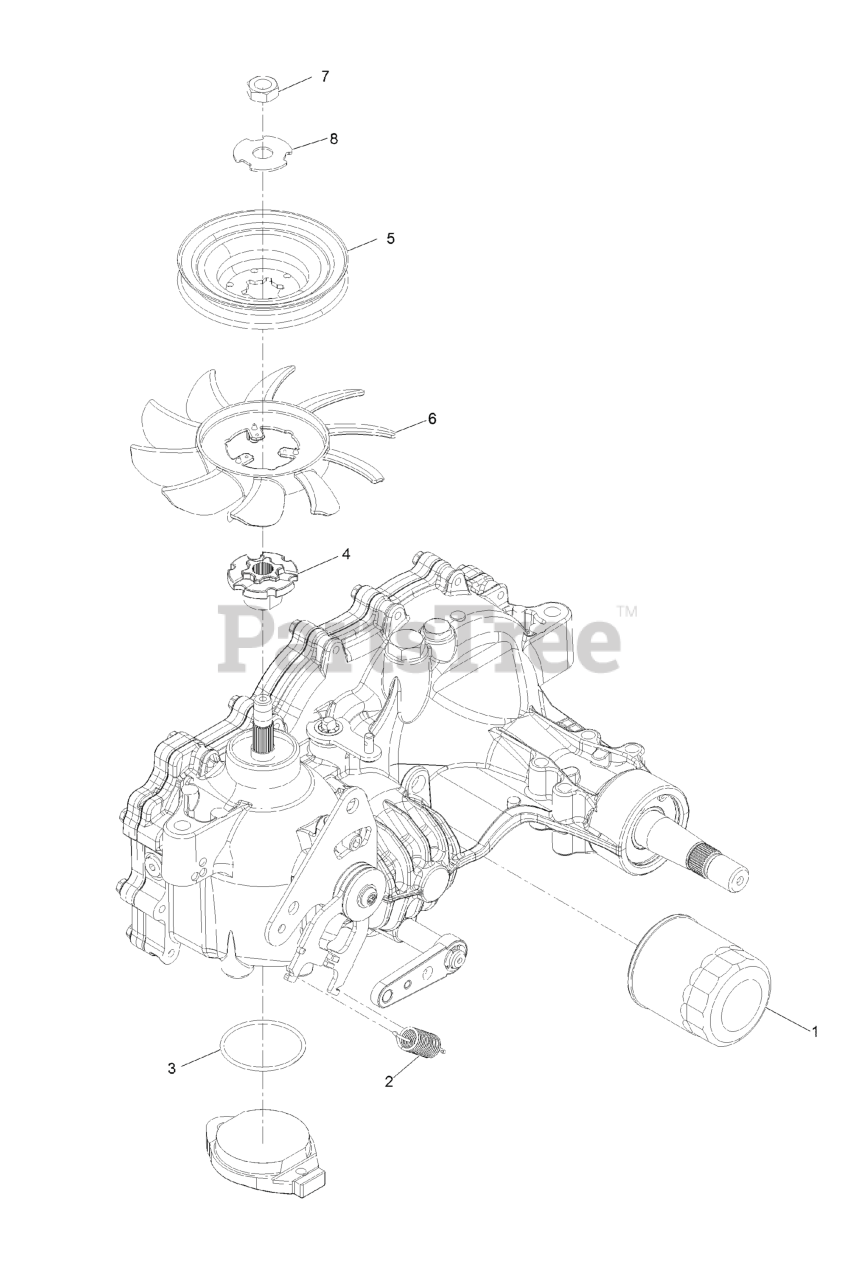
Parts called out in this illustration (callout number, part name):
1	ELEMENT-OIL FILTER, HYD
2	SPRING-EXTENSION
3	O RING-SEAL
4	HUB-PULLEY
8	WASHER-SLOTTED
